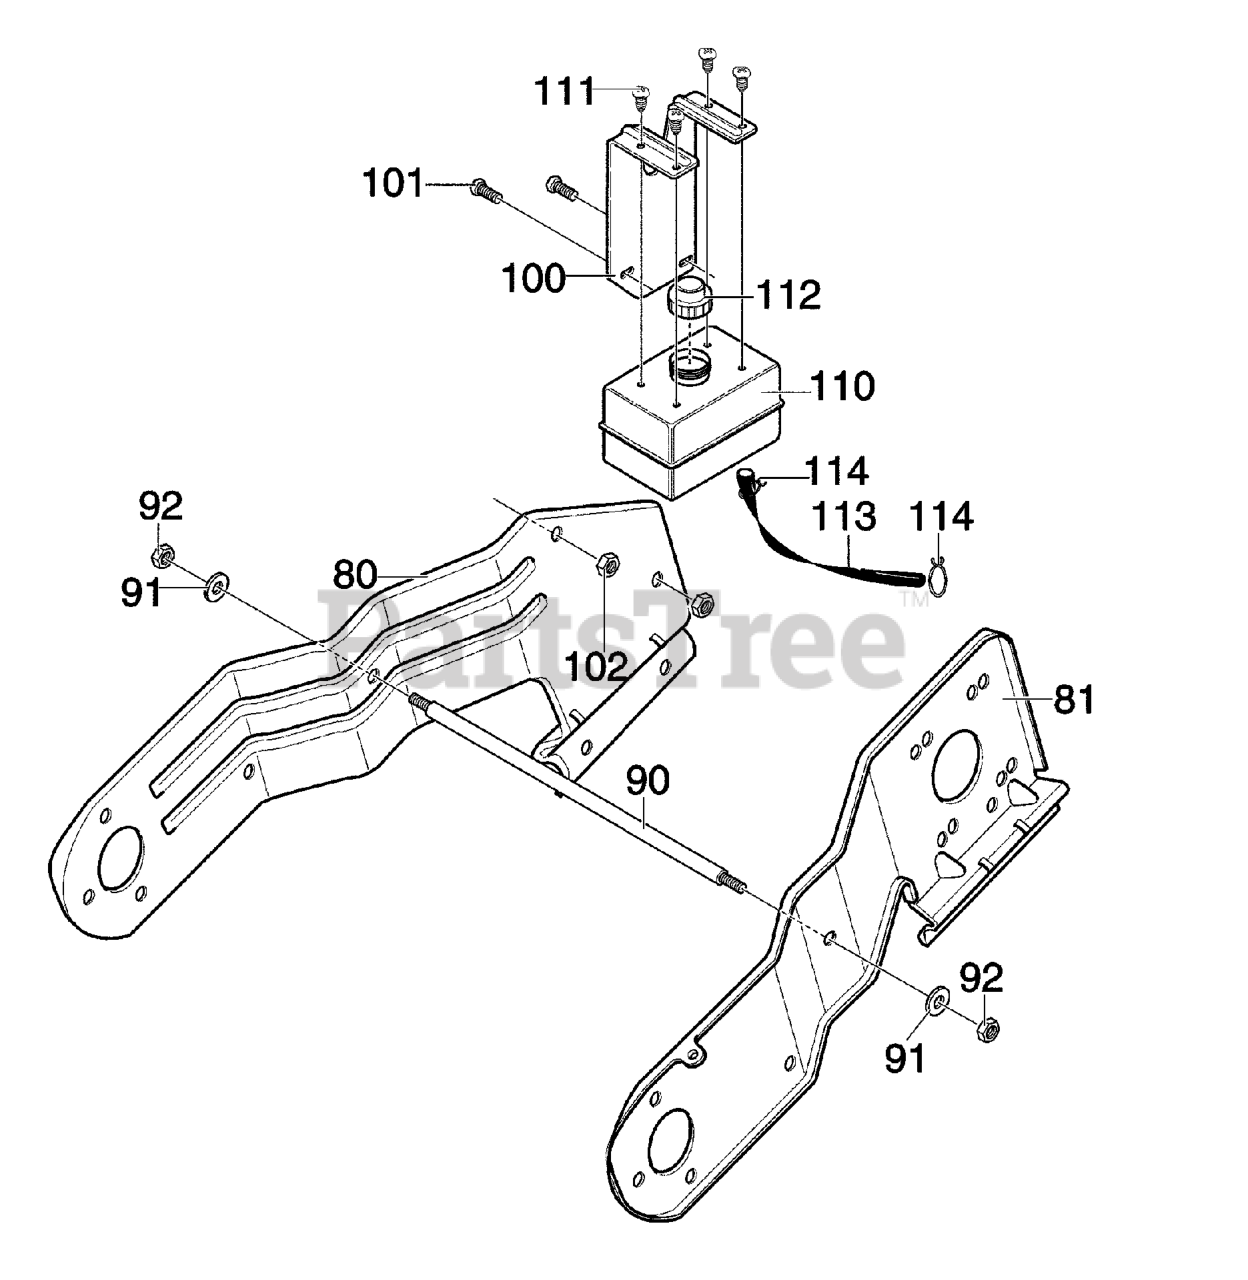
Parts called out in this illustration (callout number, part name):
80	FRAME SIDE SUPPORT RH
81	FRAME SIDE SUPPORT LH
90	ROD, SUPPORT
91	WASHER
92	NUT, 3/8-16
100	BRACKET, GAS TANK
101	SCREW, 1/4-20X.75
102	NUT, 1/4-20
110	TANK, FUEL
112	CAP, GAS-RED
113	TUBING 11.50 IN.
114	CLAMP, FUEL LINE
